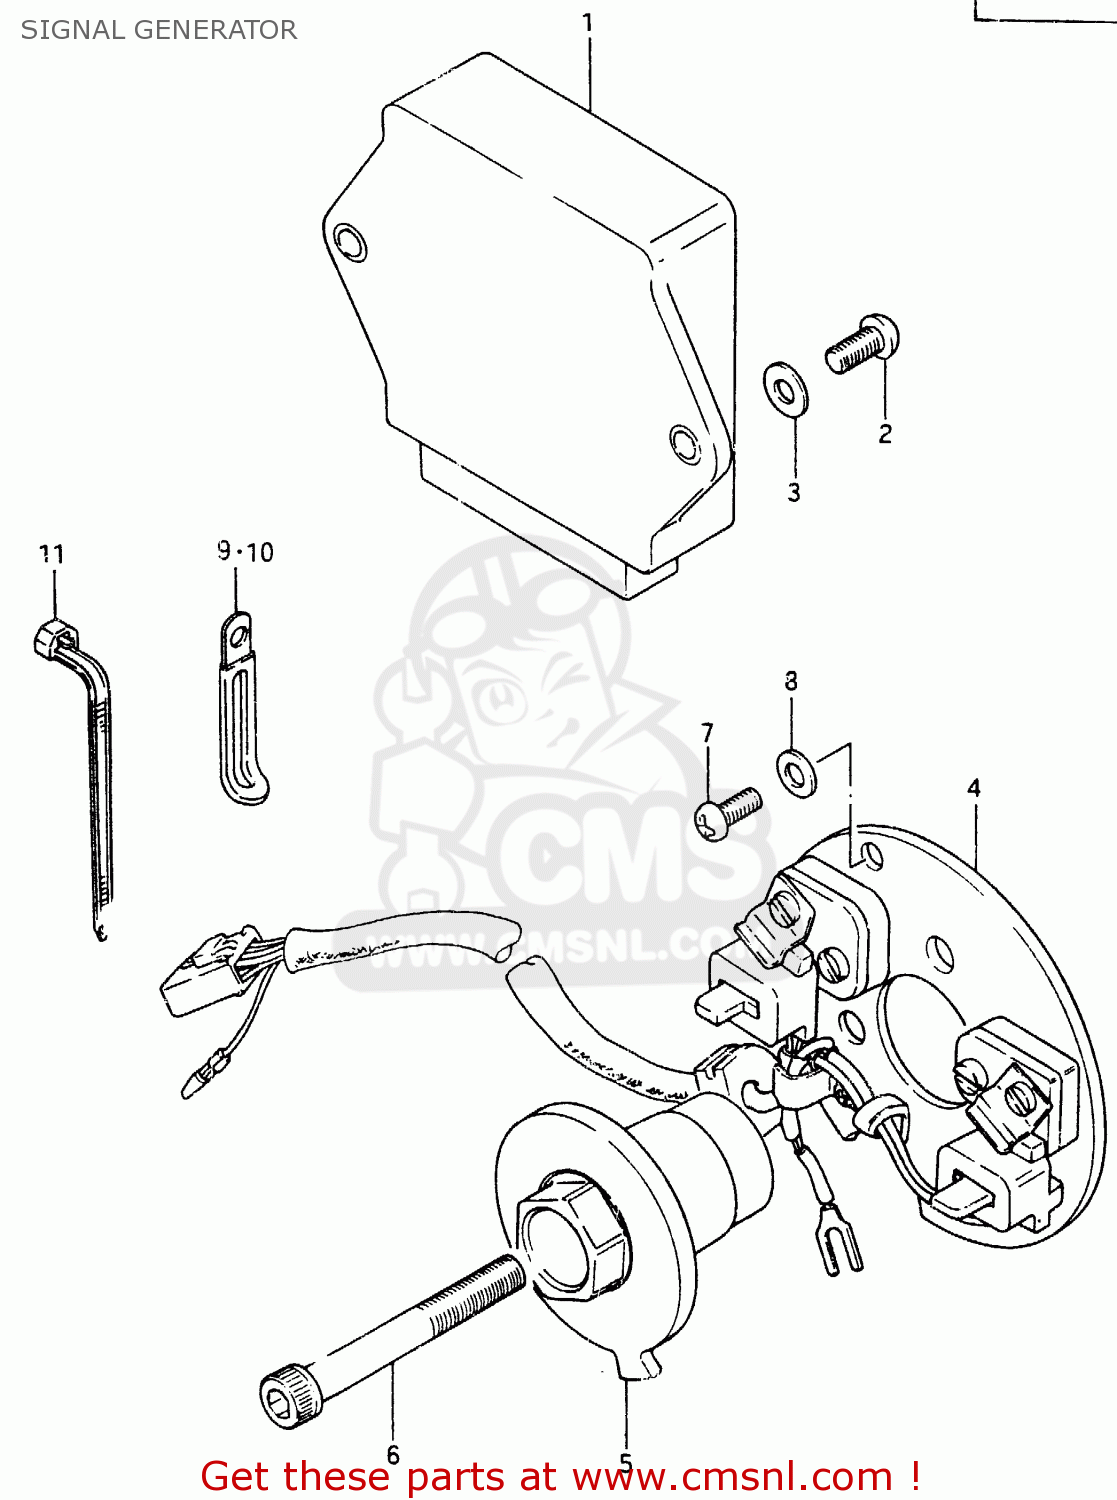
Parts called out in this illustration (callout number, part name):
1	IGNITER UNIT ASSEMBLY
2	SCREW
3	WASHER, LOWER
4	STATOR,SIGNAL GENERATOR
5	ROTOR,SIGNAL
6	BOLT
7	SCREW(5X12)
8	WASHER(5.5X10X0.8)
9	CLAMP
10	CLAMP
11	CLAMP(L:125)
